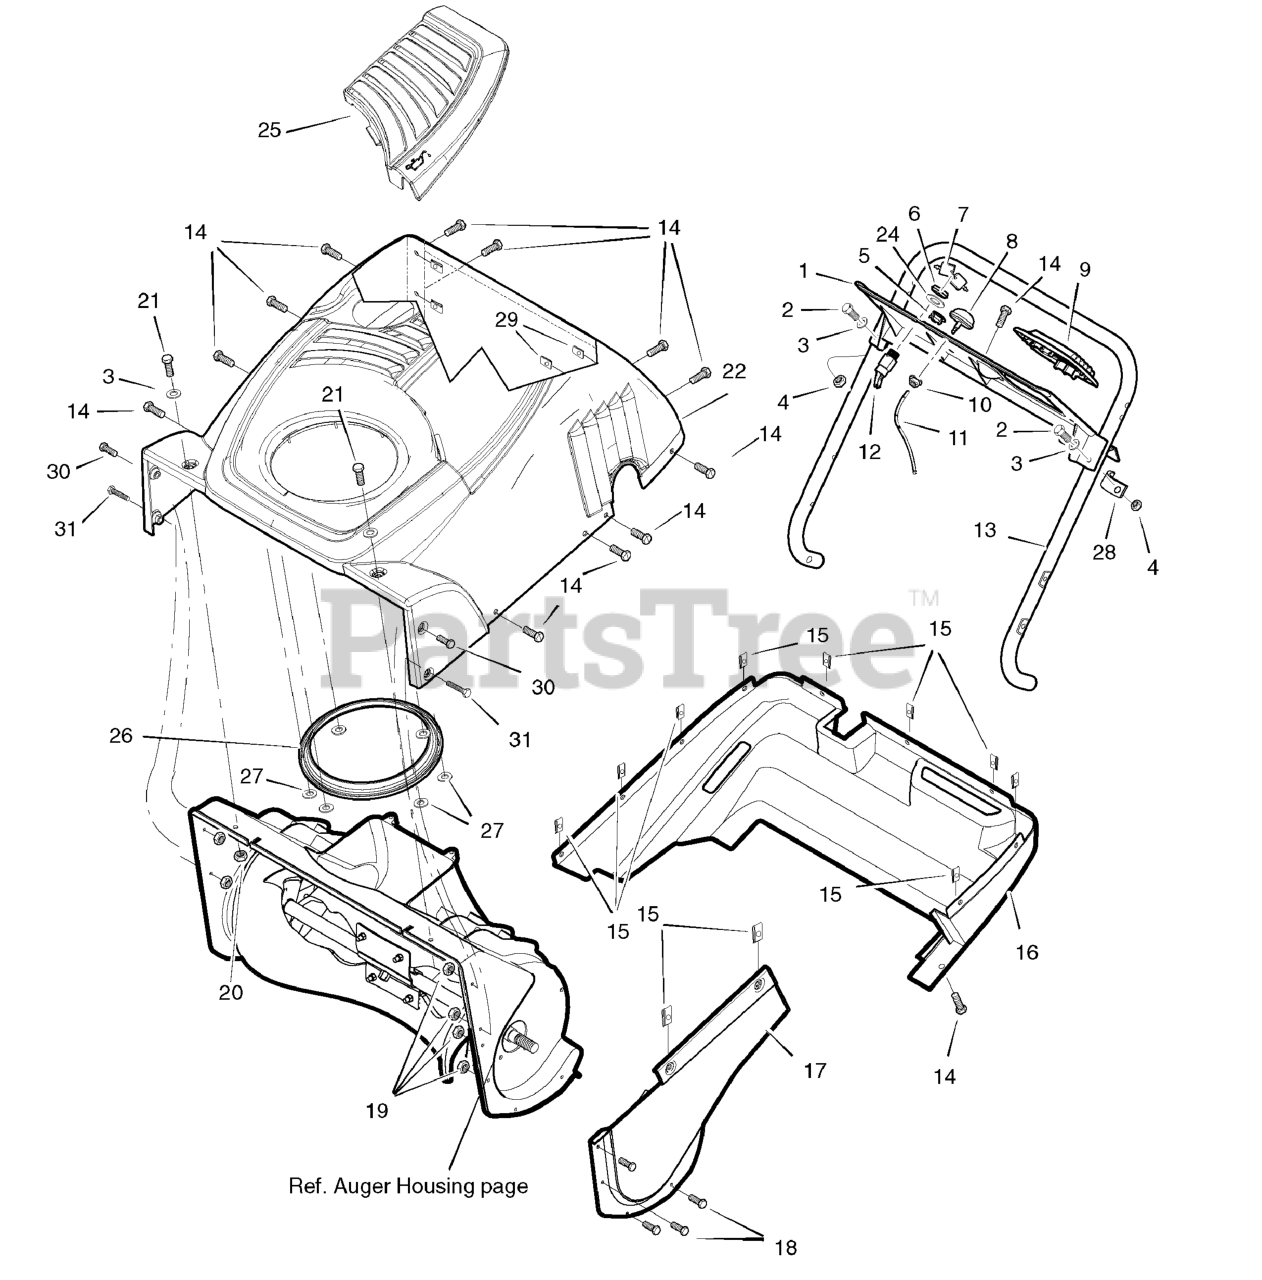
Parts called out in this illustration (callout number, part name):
1	Panel, Control
2	Screw 1/4-20 x 1.62
3	Washer
4	Nut,1/4-20
5	Bushing, Chute Crank
6	Nut, 5/8-32
7	SET, Key
8	Bulb, Fuel Primer
9	Panel, Cover Access
10	Nut, Keps 1/4-20
11	Hose, Primer 9.5"
12	Switch, Ignition
13	Handle, Lower
14	Screw 1/4-14 x .75
15	J-Nut 1/4-10
16	Cover, Bottom
17	Cover, Belt
18	Screw 10-24 x .5
19	Locknut, Hex 10 -24
20	Locknut, Hex 1/4-20
21	Screw 1/4-20 x .63
22	Cover, Top
25	Cover, Oil Access
26	Gasket, Chute Ring
27	Push Nut
28	Clamp, Cable
29	J-Nut, 1/4-10 x .70
30	Screw, 10-24 x .72
31	Screw, 10-24 x .95
